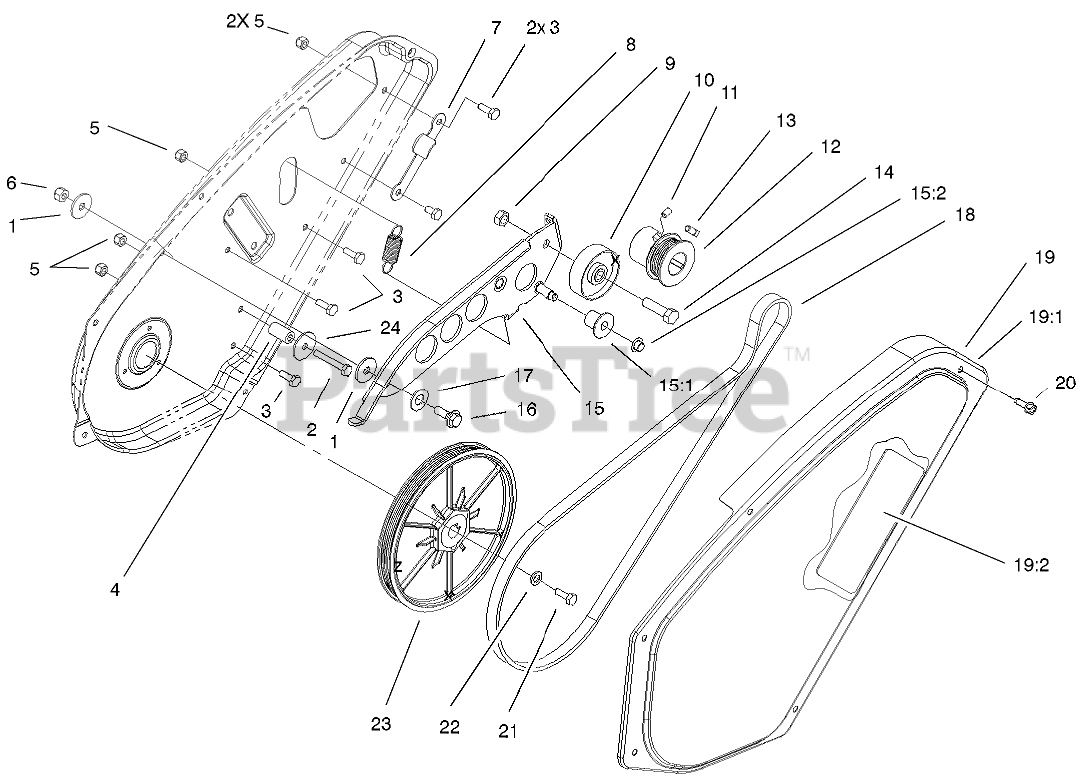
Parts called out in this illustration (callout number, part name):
1	WASHER-PIVOT
2	SCREW-HH
3	SCREW-HH
4	SLEEVE-GUIDE, BELT
5	NUT-LOCK, NI
6	NUT-LOCK, NI
7	BELT-GUIDE
8	SPRING
9	NUT-LOCK, CONE
10	PULLEY-IDLER
11	SCREW-HSH
12	SCREW-SQH
13	PULLEY
14	SCREW-HH
15	BRAKE-ARM
15:1	ROLLER-BRAKE
15:2	NUT-PUSH
16	SCREW-SHOULDER
17	WASHER
18	BELT-DRIVE
19	DRIVE COVER ASM
19:1	DECAL-WARNING
19:2	DECAL-ROUTING, BELT
20	SCREW-HWHTF
21	SCREW-HH
22	WASHER-BELLEVILLE
23	PULLEY-ROTOR
24	WASHER-FLAT
